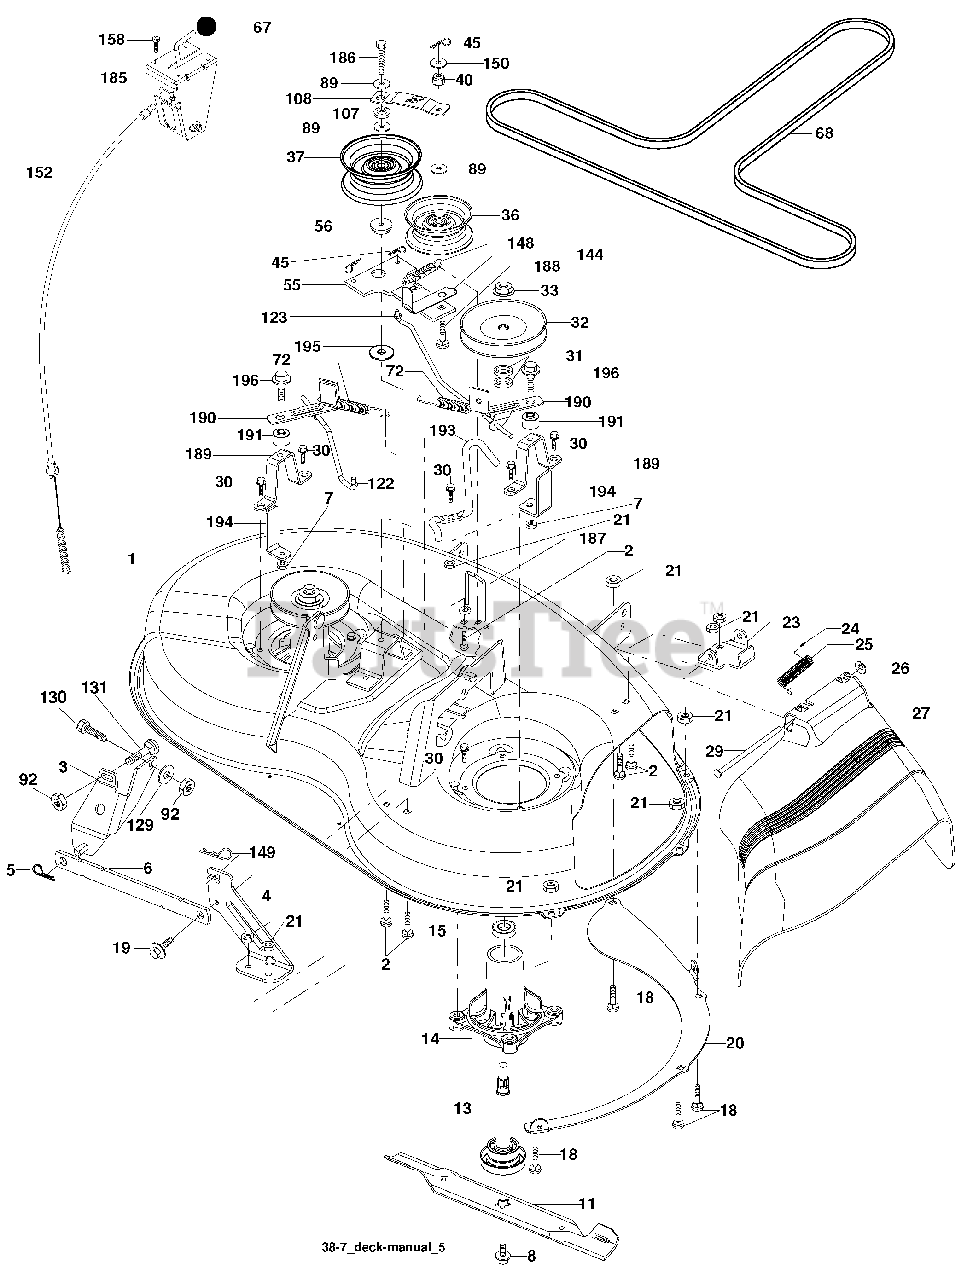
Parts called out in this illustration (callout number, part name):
1	Mower Housing Assembly
2	Bolt Carriage 5/16-18 x 3/4
3	Bracket Asm Fr. Sway Bar
4	Bracket Deck Sway Bar 38"/42"
5	Retainer Spring
6	Bar Sway Deck
7	Nut Lock Hex w/Insert 5/16-18 unc
8	Bolt 3/8-24 x 1.25 Gr. 8
11	Blade Mower
13	Shaft Assembly, Mandrel, Vented
14	Housing, Mandrel, Vented
15	Bearing, Ball, Mandrel
18	Blade Rdhd Sqnk 5/16-18 x 5/8
19	Bolt, Shoulder
20	Baffle Vortex Front
21	Nut
23	Bracket, Mower Deflector
24	Cap, Sleeve
25	Spring, Torsion, Deflector
26	Nut, Push
27	Shield, Deflector
29	Rod, Hinge
30	Screw Thdrol.
31	Washer, Spacer
32	Pulley, Mandrel
33	Nut, Toplock
36	Pulley, Idler, Flat
37	Pulley, Idler Flat
40	Nut, Crownlock 3/8-16 unc
45	Retainer
55	Idler Arm Assembly
56	Spacer, Retainer
67	Knob
68	V-Belt
72	Spring Brake Return
89	Washer 13/32 x 13/16 x 11 Ga.
92	Nut Lock 3/8-16
107	Spacer Retainer
108	Stiffener, Idler Arm
122	Rod, Brake LH
123	Rod, Brake RH
129	Washer 3/8
130	Bolt Hex 3/8-16 x 1 Gr. 5
131	Bolt Carr 3/8-16 x 1
144	Keeper Belt Idler Tension
148	Spring Return Idler
149	Retainer Spring Yellow
150	Washer 9/32 x 3/4 x 10 Ga.
152	Clutch Cable 38"
158	Screw Hex Thd Cut 1/4-20 x 1/2
185	Head Asm Cable Clutch
186	Screw Hex Wsh Thdrol 3/8-16 x 2-3/4
187	Keeper Belt M Shape
188	Bolt Carriage Idler
189	Brake Stand
190	Brake Arm
191	Brake Spacer
193	Keeper Belt Rh Mandrel
194	Brake Guard
195	Washer 13/32 x 2 x 10 Ga.
196	Bolt/Washer Asm. 5/16-18
196	Mandrel Assembly
196	Brake Assembly
196	Replacement Mower, Complete
